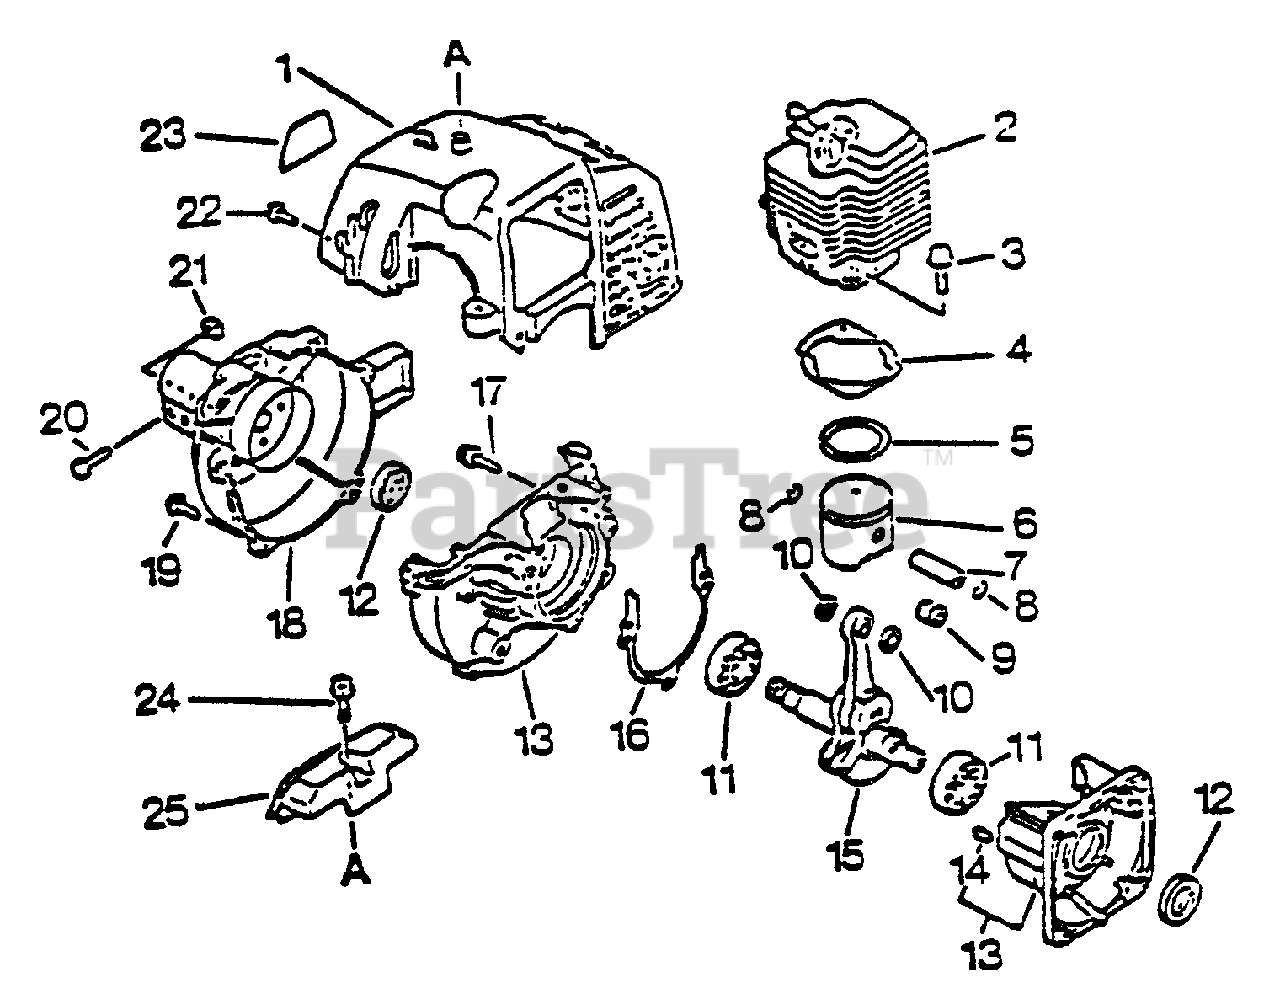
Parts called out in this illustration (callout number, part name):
1	COVER, ENGINE - GRAY
2	CYLINDER
3	SCREW - 5X22
4	GASKET, CYLINDER
5	PISTON KIT
6	RING, PISTON
7	PIN, PISTON
8	RING, RETAINING
9	BEARING, NEEDLE
10	SPACER, PISTON
11	BEARING, BALL - 6201
12	SEAL, OIL
13	CRANKCASE KIT
14	PIN - LOCATING
15	CRANKSHAFT ASSY
16	GASKET, CRANKCASE
17	SCREW - 5X28
18	FAN CASE ASSY
19	SCREW - 4X18
20	BOLT - 5X28
21	NUT - 5 -- SQUARE
22	SCREW - 4X12
23	LABEL - MODEL
24	SCREW - 5X16 -- TAPPING
25	GUARD, TOP - BLACK
